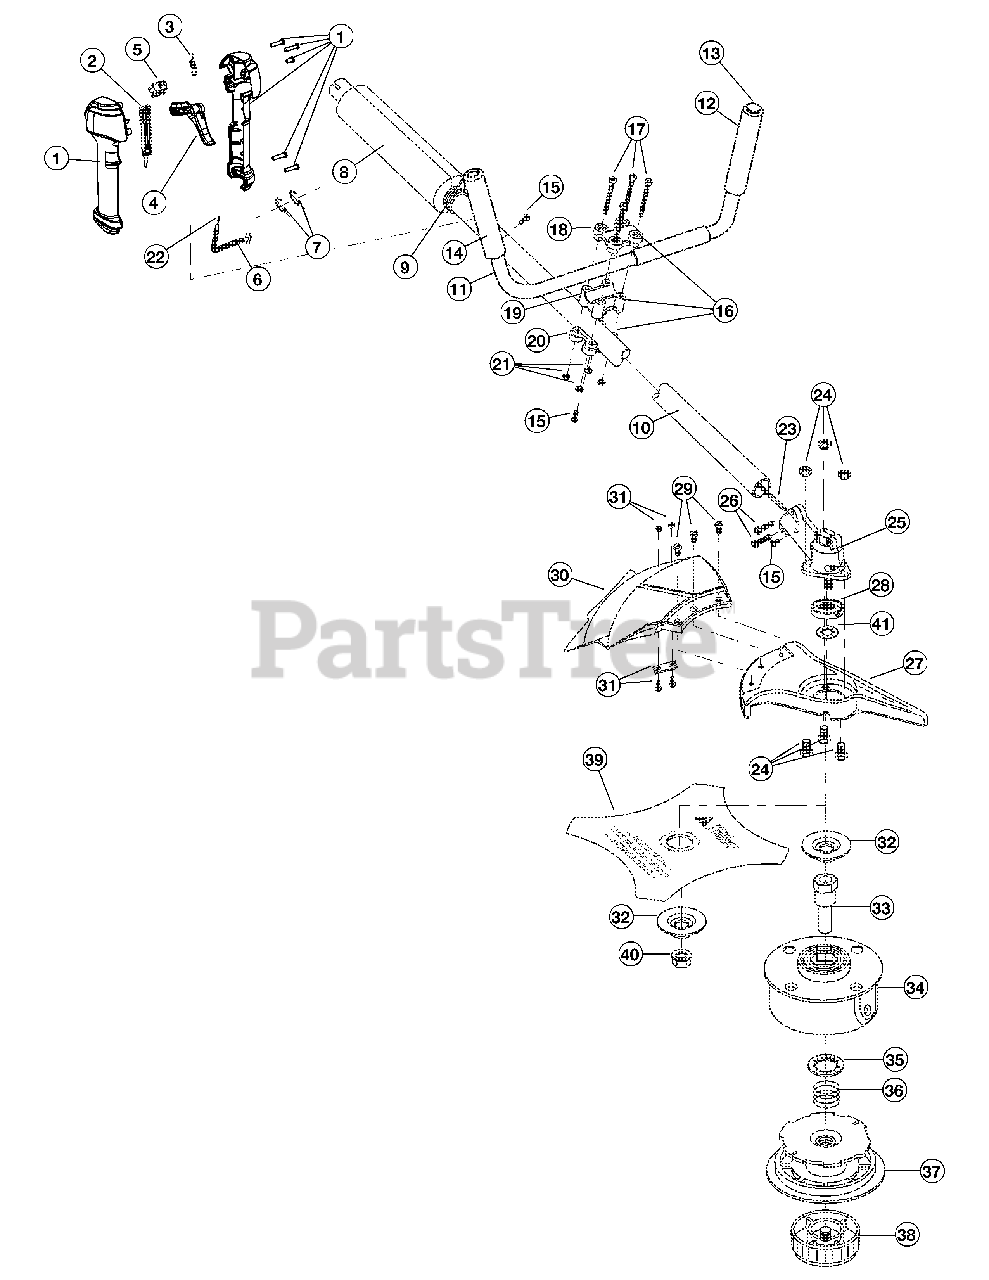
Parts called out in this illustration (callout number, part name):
1	Throttle Housing Assembly (includes 2-5)
2	Throttle Trigger Lock-Out
3	Throttle Trigger Spring
4	Throttle Trigger
5	Switch Assembly
6	Wire Cover 1ft
7	Cable Clamp
8	Foam Grip & Cover
9	Harness Clip
10	Drive Shaft Housing Assembly
11	Bullhorn Handle Assembly (includes 12-15)
13	Plug
14	Adapter
15	Anti-Rotation Screw
16	Handle Bracket Assembly (includes 15 & 17-21)
18	Upper Handle Clamp
19	Middle Handle Clamp
20	Lower Handle Clamp
22	Throttle Cable
23	Flexible Drive Shaft
24	Shield Mount Screw Assembly
25	2 Piece Gearbox Assembly (includes 15, 26, 28 & 41)
26	Gear Box Screw
27	Blade Shield/Shield Mount
28	Blade Driver
29	Shield Mounting Screw
30	Shield Assembly (includes 31)
31	Blade Assembly
32	Retaining Washer
33	Spool Shaft
34	Outer Spool Assembly (includes 35)
35	Retainer
37	Inner Reel
38	Bump Head Knob Assembly
39	4-Tooth Blade
40	Nut
41	Palnut
